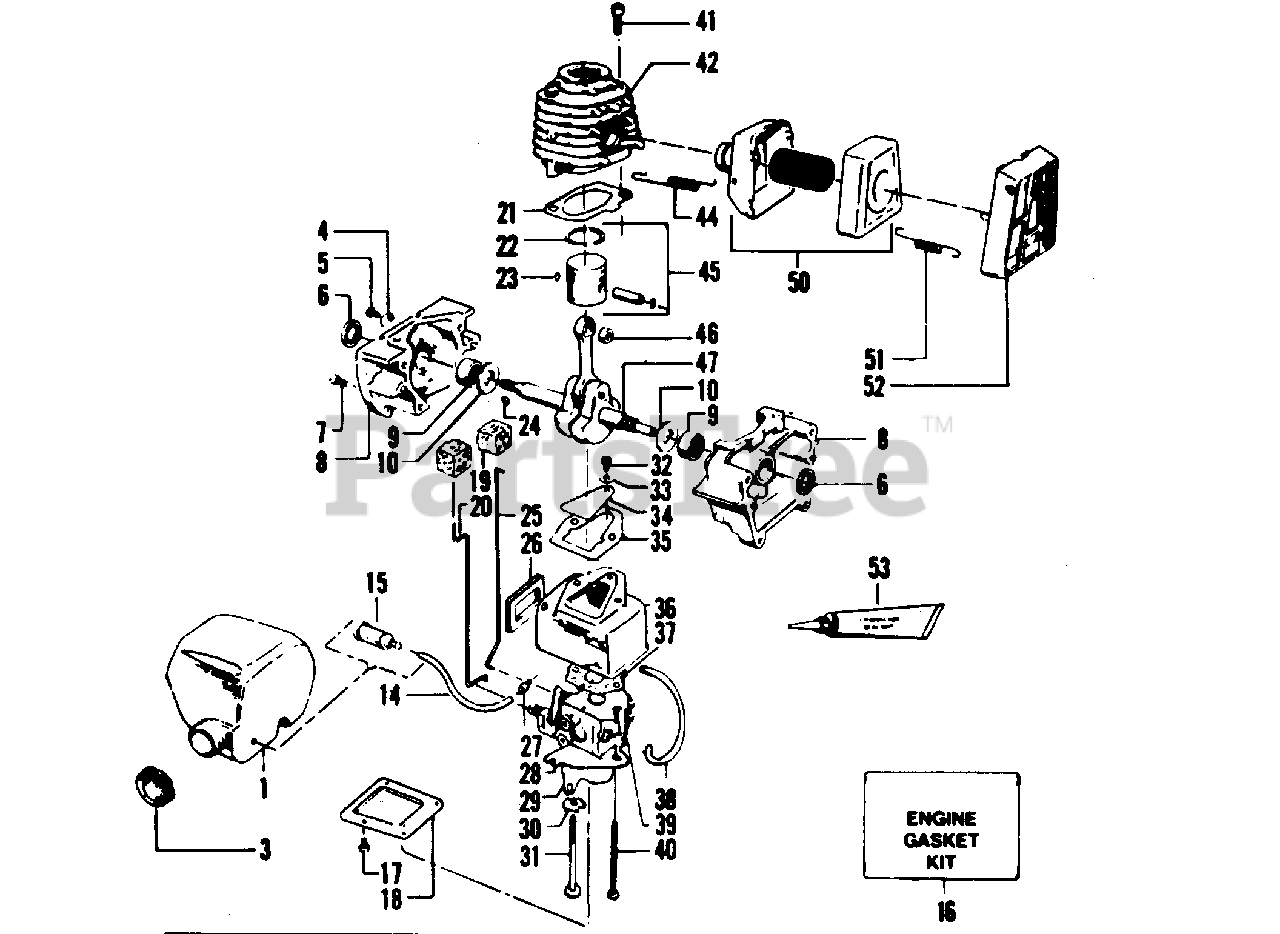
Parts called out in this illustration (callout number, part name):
1	Fuel Tank Ass'y. (Inc.3, 14, 15 & 27)
3	Fuel Cap Assembly (Incl. O-Ring)
4	Clamp-Choke Wire
5	Screw-8-32x5/16-Pan Hd. Choke Rod Clamp
6	Seal-Crankcase
7	Screw-Crankcase
8	Crankcase Assembly (Inc.6, 9 & Qty. 4 of #7)
9	Bearing-Crankcase
10	Washer-Thrust-Crankcase
14	Line Kit
15	Fuel Pick-up Assembly
16	Kit-Engine Gasket
17	Screw-8-18x9/16"-Pan Hd.-Carburetor Case Cover
18	Cover-Carburetor Case
19	Boot-Throttle-Choke Wire
20	Choke Wire
21	Gasket-Cylinder
22	Ring-Piston
23	Retainer-Wrist Pin
24	Key-Flywheel
25	Throttle Wire
26	Seal-Carburetor Case
27	Fuel Line Fitting
28	Choke Wire Guide Plate
29	Choke Shutter
30	Washer-Wave
31	Screw-10-24x2-1/8"-Fil. Hd.-Carburetor Shoulder
32	Screw-6-19-5/16"-Pan Hd.-Reed Valve
33	Washer-Reed Valve Screw
34	Reed Valve
35	Gasket-Carburetor Case to Crankcase
36	Carburetor Housing
37	Gasket-Carburetor
38	Line Kit
39	Carburetor
40	Screw-10-24x1-7/8"-Fil. Hd.-Carburetor
41	Screw-1/4-20x3/4"-Hex Shocket Hd.-Cylinder
42	Cylinder
44	Spring-Muffler Detachment
45	Piston Kit (Incl.#22, 23 & Pin)
46	Bearing-Wrist Pin
47	Crankshaft & Rod Assembly (Inc.46)
50	Muffler Ass'y.
51	Spring-Muffler Guard
52	Guard-Muffler
53	Sealant-Crankcase (Not Supplied with Unit)
